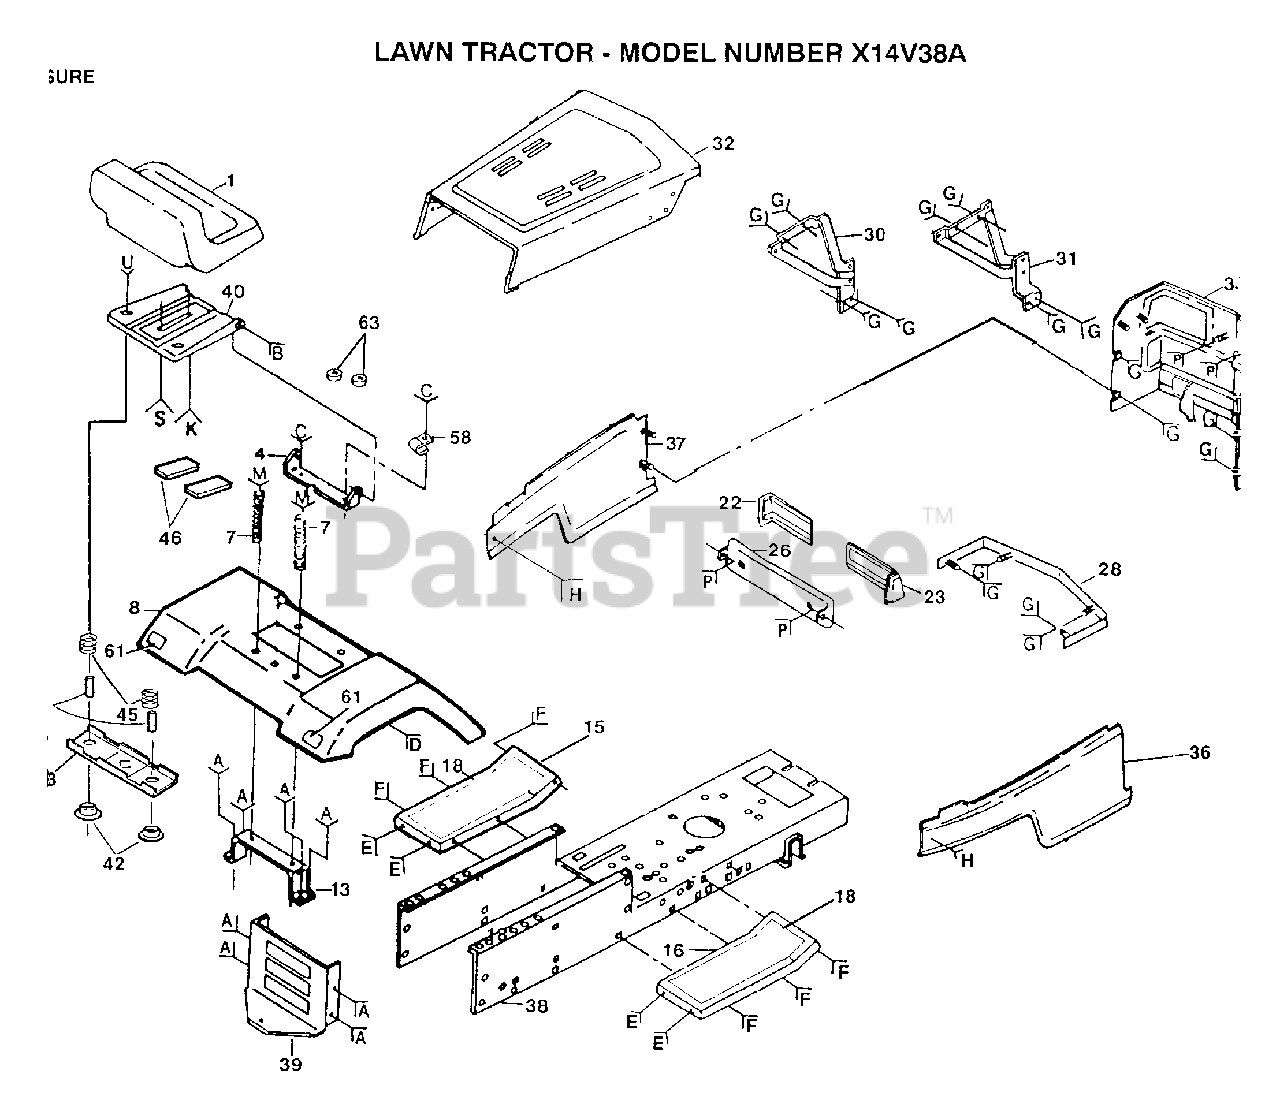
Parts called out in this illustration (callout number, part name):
7	SPRING COMPRESSIO
18	PAD FOOTREST T
28	STRAP, ASM., GRILL
30	"HINGE,HOOD,LH T"
31	"HINGE,HOOD,RH T"
36	"SIDE PANEL,RH"
37	"SIDE PANEL,LH"
38	CHASSIS ASSY
39	DRAWBAR LT/YT
42	BUSHING
45	SPRING
46	STRIP FORM
61	REFLECTOR-TAIL YT
63	CAP SPRING
